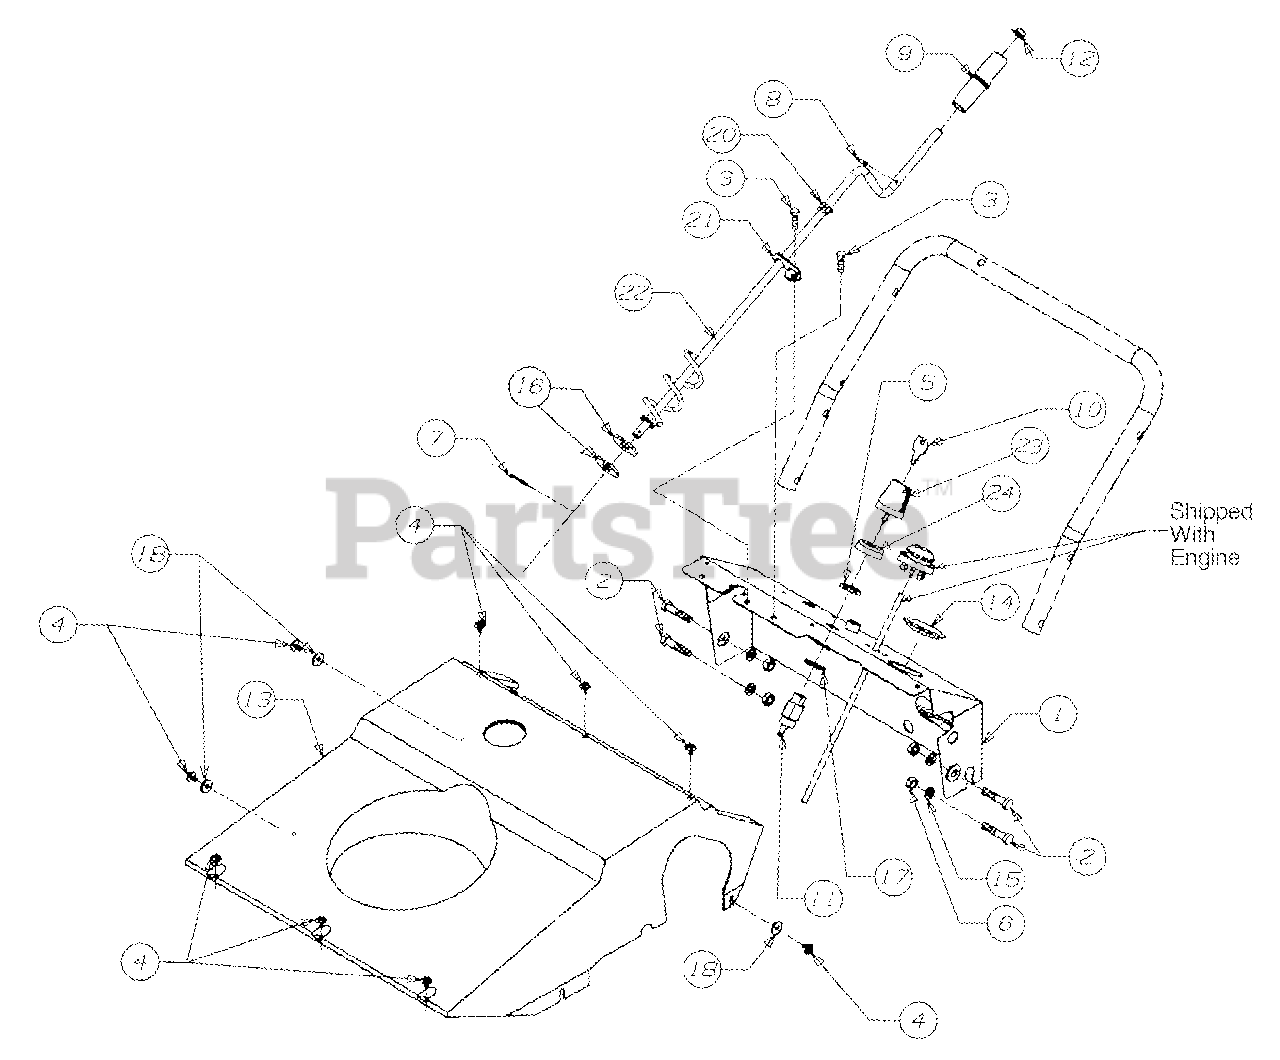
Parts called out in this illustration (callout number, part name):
2	Screw-Hex
3	Screw-Hex Tap
4	Screw-Hex Tap
7	Pin-Cotter
8	Pin Roll
9	Knob-Chute Crank
10	Key-Ignition - Std.
11	Switch-Key
13	Shroud -Beige
14	Plug
15	Washer Lock
17	Washer Internal Lock
18	Washer Flat
20	Bushing
21	Bracket Chute Crank
22	Crank Ass'y. Chute
23	Key - Ignition w/Bell Cover
24	Cover - Ignition Switch
